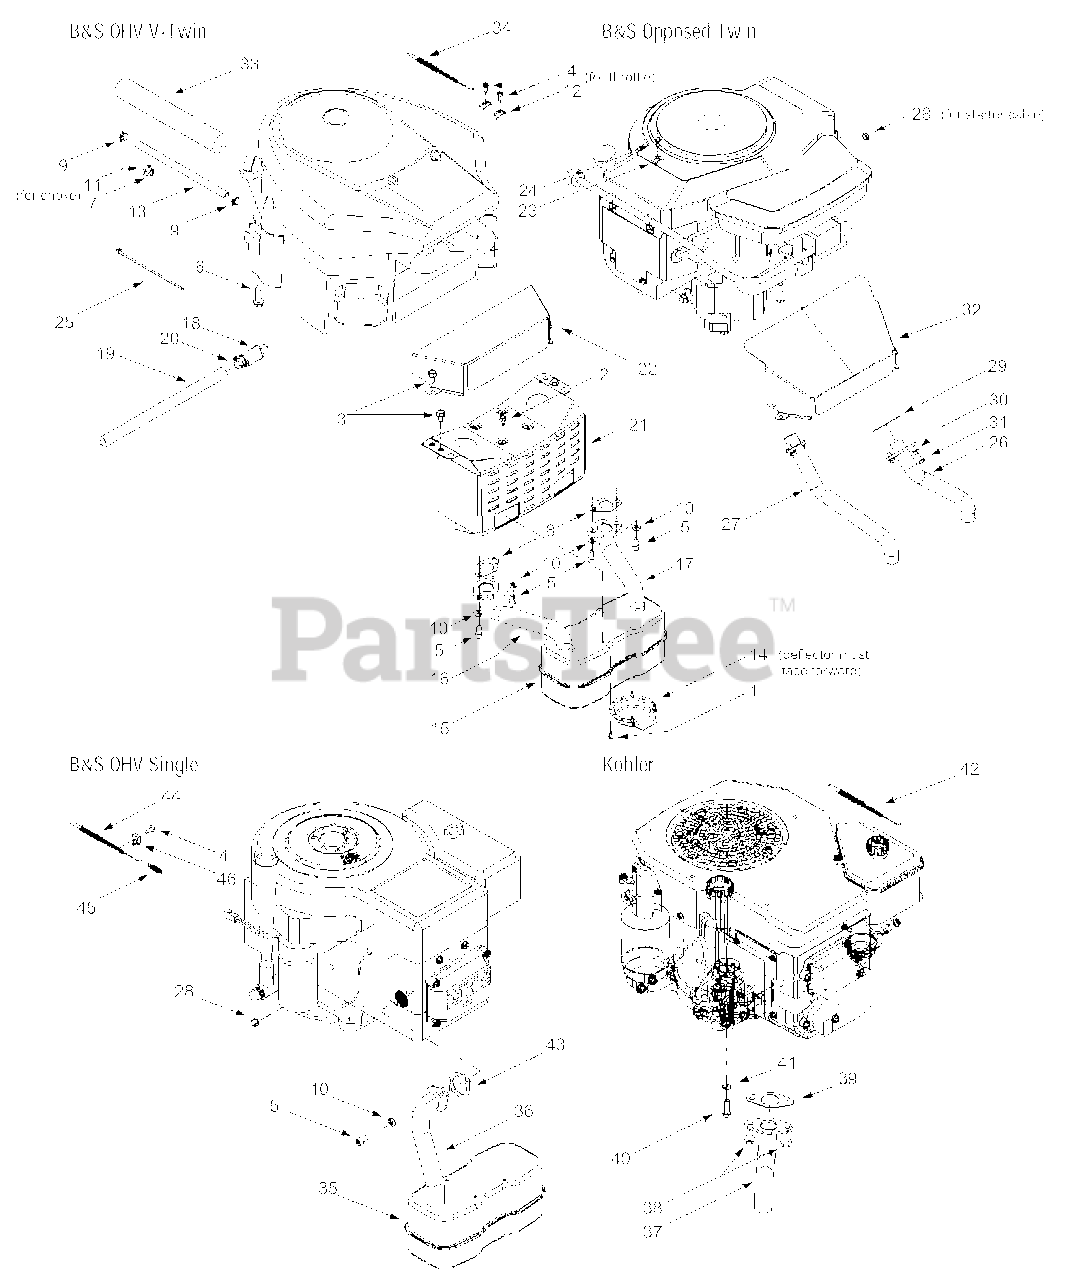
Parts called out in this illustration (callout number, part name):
1	Self-tapping Screw, #8-18 x .50
2	Self-tapping Screw, 1/4-20 x .50
3	Self-tapping Screw, 5/16-18 x .625
4	Screw, #10-32 x .625 (B&S OHV V-Twin)
5	Socket Cap Screw, 5/16-18 x .625
6	Self-tapping Screw, 3/8-16 x 1.25
7	Hex Nut, 3/8-16
8	Exhaust Gasket (B&S OHV V-Twin)
9	Hose Clamp
10	Lock Washer, 5/16
11	Lock Washer, .406 x .875 x .059
12	Casing Clamp (B&S OHV V-Twin)
13	Fuel Line Hose
14	Muffler Deflector
15	Muffler, Twin Inlet (B&S Opposed Twin & OHV V-Twin)
16	RH Exhaust Pipe (B&S OHV V-Twin)
17	LH Exhaust Pipe (B&S OHV V-Twin)
18	Oil Drain Valve
19	Oil Drain Hose
20	Oil Drain Cap
22	Engine Heat Shield (B&S OHV V-Twin)
23	Clamp, 9/16 (B&S Opposed Twin)
24	Screw, #10-16 x .5 (B&S Opposed Twin)
25	Cable Tie
26	LH Exhaust Pipe (B&S Opposed Twin)
27	RH Exhaust Pipe (B&S Opposed Twin)
28	Hex Sems Nut, 1/4-20 (B&S Opposed Twin & OHV Single)
29	Exhaust Gasket (B&S Opposed Twin)
30	Lock Washer, 1/4 (B&S Opposed Twin)
31	Hex Screw, 1/4-20 x .750 (B&S Opposed Twin)
33	Foam, .625 x 1.5 x 10 (fits over fuel line)
34	Throttle Cable (B&S Opposed Twin & OHV V-Twin)
35	Muffler, Single Inlet (B&S OHV Single & Kohler)
36	Exhaust Pipe (B&S OHV Single)
37	Exhaust Pipe (Kohler)
38	Flange Nut, 8mm (Kohler)
39	Exhaust Gasket (Kohler)
40	Hex Cap Screw, 8mm (Kohler)
41	External Lock Washer (Kohler)
42	Throttle Cable (Kohler)
43	Exhaust Gasket (B&S OHV Single)
44	Throttle Cable (B&S OHV Single)
45	Extension Spring, .275 x 1.25 (B&S OHV Single)
46	Casing Clamp (B&S OHV Single)
